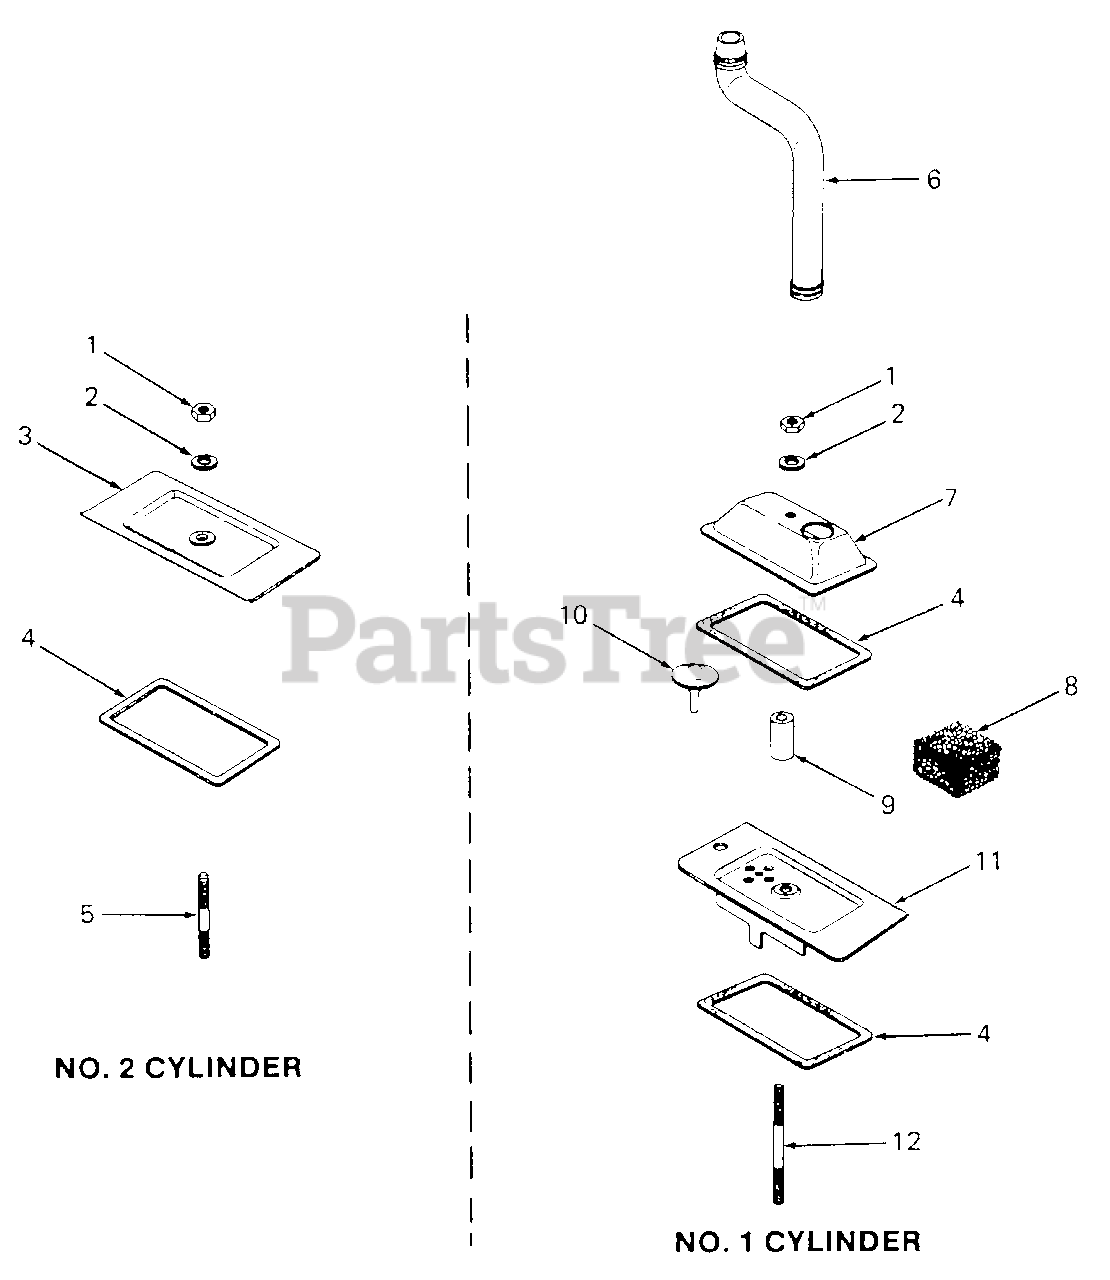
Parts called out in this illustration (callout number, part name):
1	Nut, Hex, 1/4-20
2	Washer, Plain, 1/4
3	Cover, #2 Cylinder Valve
4	Gasket, Valve Cover
5	Stud, #2 Cylinder Valve Cover, 1/4-20 X 2-1/4
6	Hose, Breather
7	Cover, #1 Upper Cylinder Valve
8	Filter, Breather
9	Seal, Breather
10	Valve, Umbrella
11	Cover, #1 Lower Cylinder Valve
12	Stud, #1 Cylinder Valve Cover, 1/4-20 X 3-1/4
